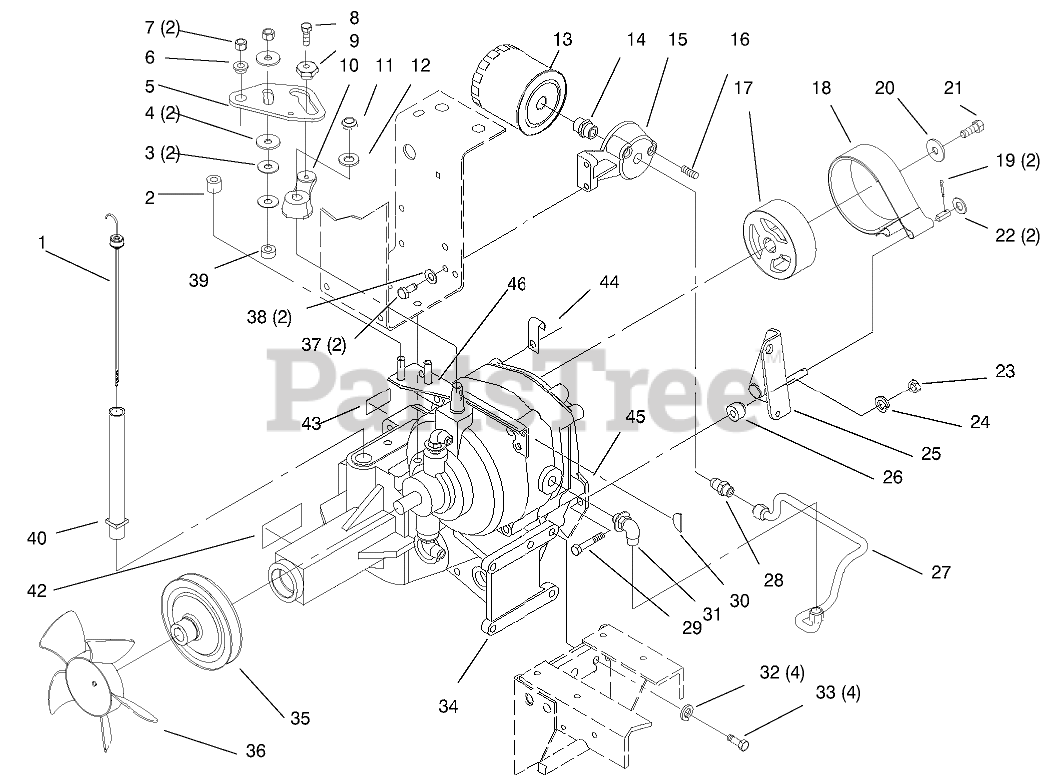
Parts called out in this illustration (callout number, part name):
1	Dipstick
2	Spacer-Pivot
3	WASHER-SPRING DISC
4	FRICTION WASHER
5	CAM-SPEED CONTROL (NS)
6	CAM-SPACER
8	Screw-HH
10	ARM-SPEED CONTROLB
11	NUT-LOCK, NI
12	WASHER-FLAT
13	OIL FILTER ASM
14	FITTING
15	BASE-FILTER
17	DRUM-BRAKE
18	ASSY-BRAKE BAND
19	PIN-COTTER
20	WASHER
21	SCREW-HH, LOCK
22	WASHER-FLAT
23	NUT-LOCK, NI
24	WASHER-FLAT
25	WA-BRAKE PIVOT B
26	BUSHING-BRAKE PIVOT
27	ASS'Y-TUBE FILTER
28	FITTING
29	SCREW-HH
30	KEY-WOODRUFF
31	ELBOW
32	WASHER-LOCK
33	SCREW-HH
34	ASM-Transaxle
35	PULLEY
36	NYLON FAN-L-CW
37	SCREW-HH
38	WASHER-LOCK
39	SPACER-FRICTION
40	NIPPLE-TRANS FILL
42	DECAL - DANGER
43	DECAL-UNIDRIVE
